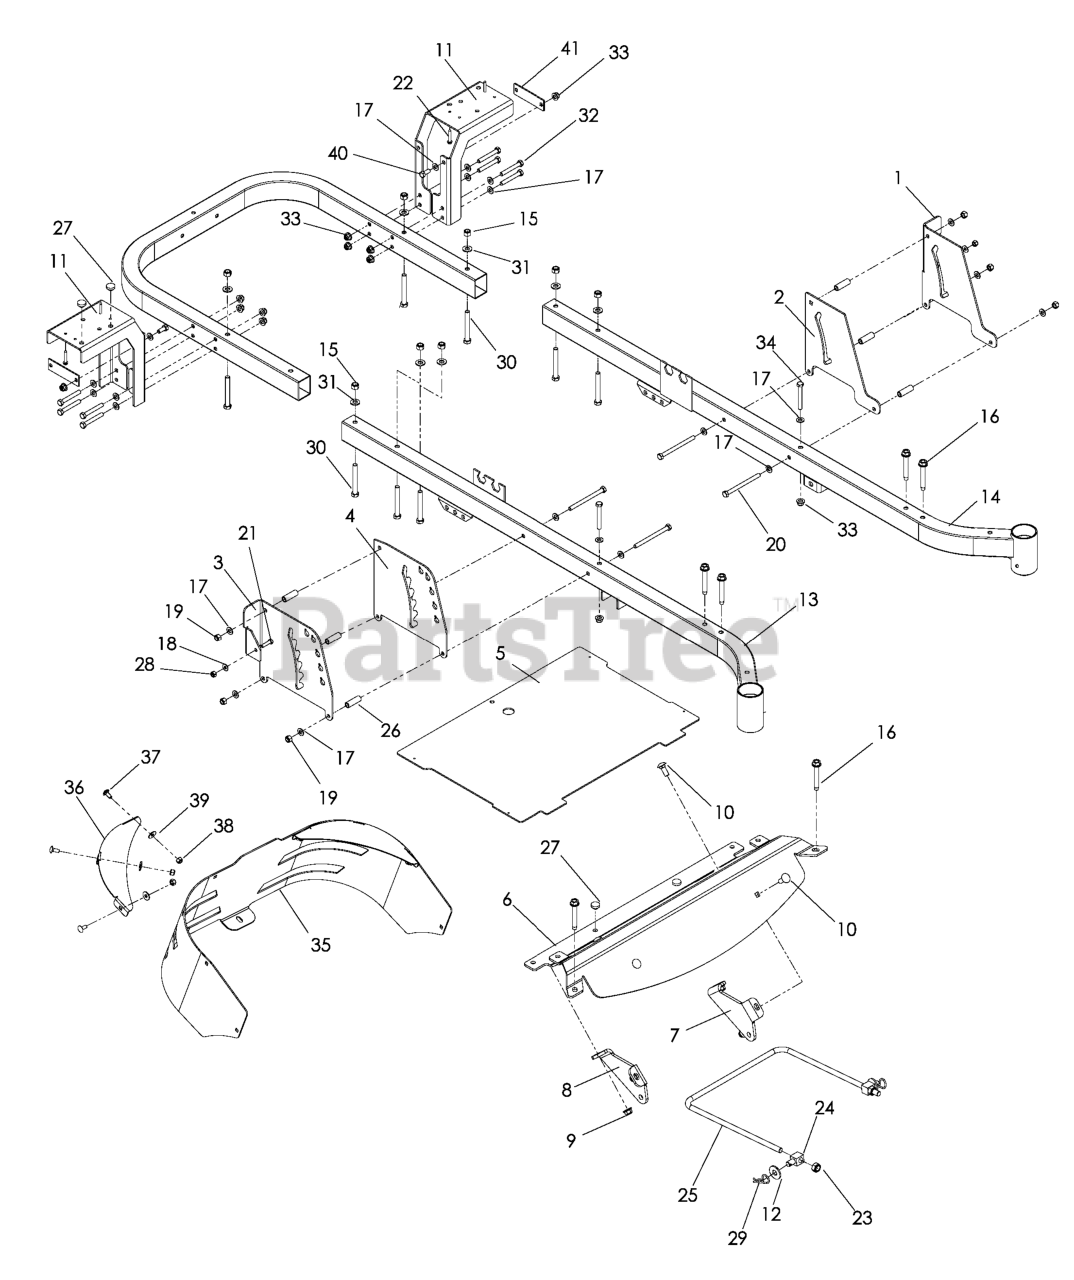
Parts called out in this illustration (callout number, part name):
1	PLATE, OUTER BRAKE, BLACK
2	PLATE, BRAKE LATCH, BLACK
3	PLATE, DECK HEIGHT, BLK EZ
4	PLATE, DECK HEIGHT, BLACK
5	FOOT PLATE w/DECALS
6	FOOT REST WIDE ORG
7	MOUNT, STRUT, RT, BLK
8	MOUNT, STRUT, LT, BLK
9	NUT 3/8-16 HEX FLG NYLOC ZD
10	RHSNB 3/8C X 1
11	SUPPORT, FENDER, BLACK
12	WASH USS FLAT 1/2
13	FRAME, RT, ORANGE
14	FRAME TUBE KZ-LT BLU
15	NUT 3/8-16 NYLOC
16	ENGINE BOLT, SPECIAL
17	FLAT WASHER 5/16 SAE
18	WASHER 1/4 SAE
19	NUT 5/16 NYLOC
20	HCS 5/16C X 4
21	HCS 1/4C X 1
22	SCR #10-12X1-1/2HEX WASH HD ZD
23	7/16-14 HEX NUT W/NYL RING ZD
25	LINK, FRONT SUSP.
26	SPACER, .334 ID X .5 OD X 1.5
27	GROMMET, BUMPER
28	NUT.1/4-20.HEX.NYLOC.ZD
29	HAIRPIN #4
30	HCS 3/8C X 3
31	WASHER 3/8 SAE FLAT
33	5/16-18 NYLOC FLANGE NUT
34	HCS 5/16C X 2-3/4
35	GUARD, REAR, ORANGE
36	SUPPORT, CORNER, ORANGE
37	RHSSNB, 1/4-20X5/8
38	NUT.1/4-20.HEX.NYLOC.ZD
39	WASHER 1/4 FLAT
40	HCS 5/16C X 3/4
41	REINFORCEMENT PLATE BLK
